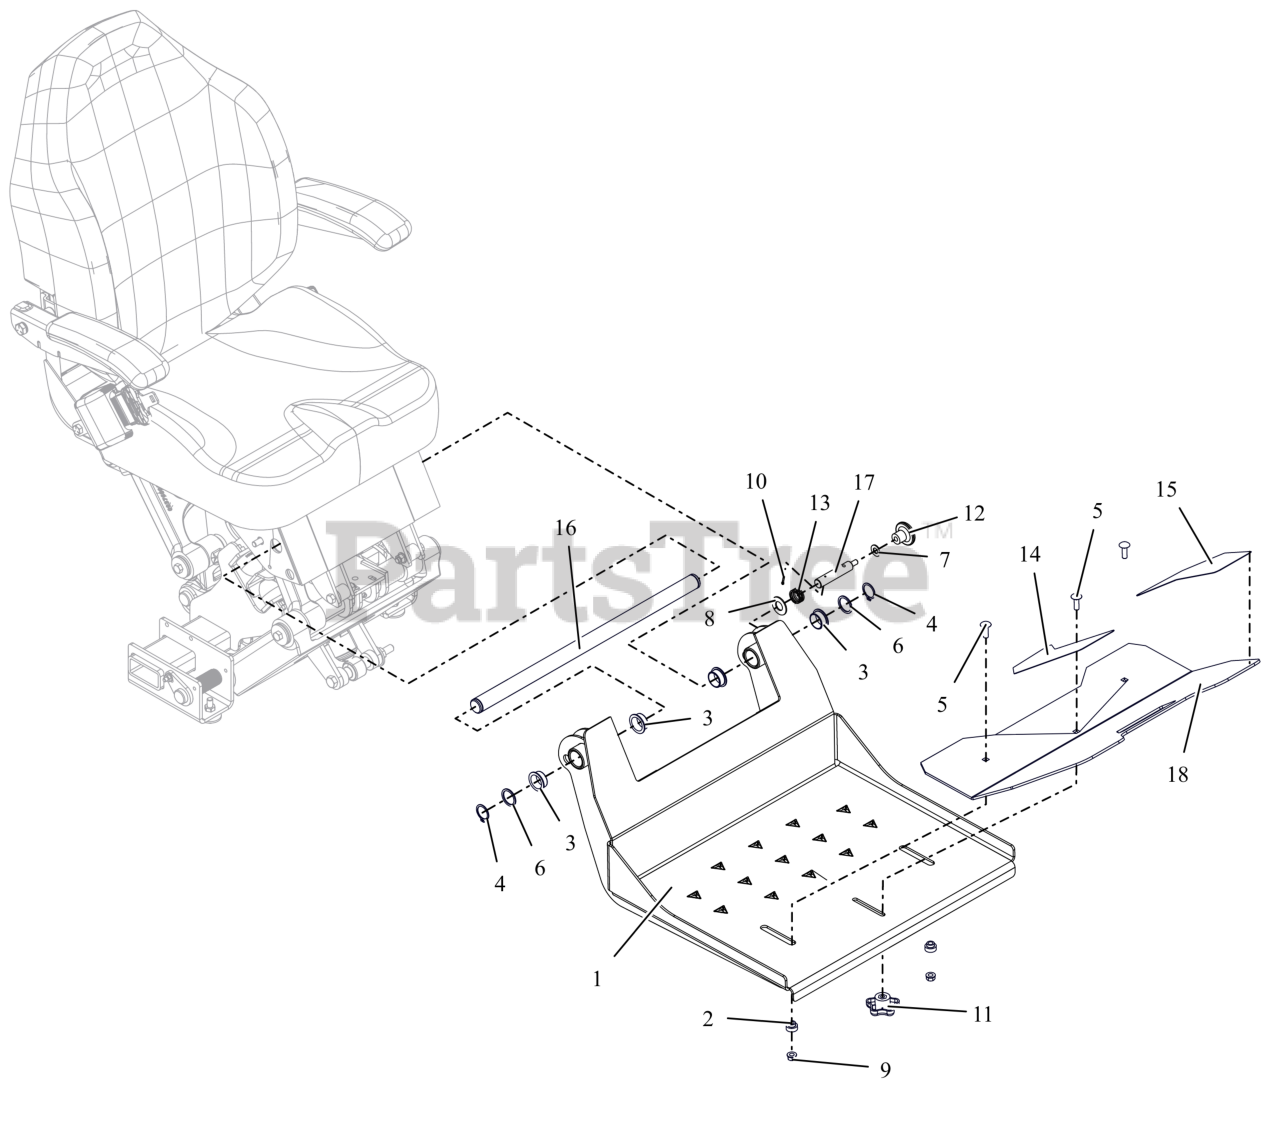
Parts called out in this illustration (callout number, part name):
1	WLDMT- FOOTREST W/SAFETY
2	SPCR, BRG .315X.500X.481X.281
3	BSHG-FLG 1.0X1.125X.50X1.375 R
4	RG-RTNG-EXT 1.00X.042
5	BLT,RHSSN .31-18X1.00 G5 ZCC
6	WSHR-FL-STL 1.01X1.25X0.068 ZCC
7	WSHR,FLT .406X.812X.065 ZCC
8	WSHR-FL-STL 0.649X1.305X0.074 Raw
9	NUT,LK-CTR-FLG .31-18 GF ZCC
10	PIN-COTR .09X1.0 PL
11	KNOB, LOCKING 5/16-18 UNC
12	KNOB, PUSH-PULL .312-18
13	SG-COMP .085X.80X1.00 WLD36
14	KIT, PT300-600 ANTI-SKID Tape
15	KIT, PT300-600 ANTI-SKID Tape
16	SHAFT, PIVOT
17	PIN, FOOTREST LOCK-UP
18	FOOTREST, ADJUSTABLE (RED) W/ SAFETY DECAL
